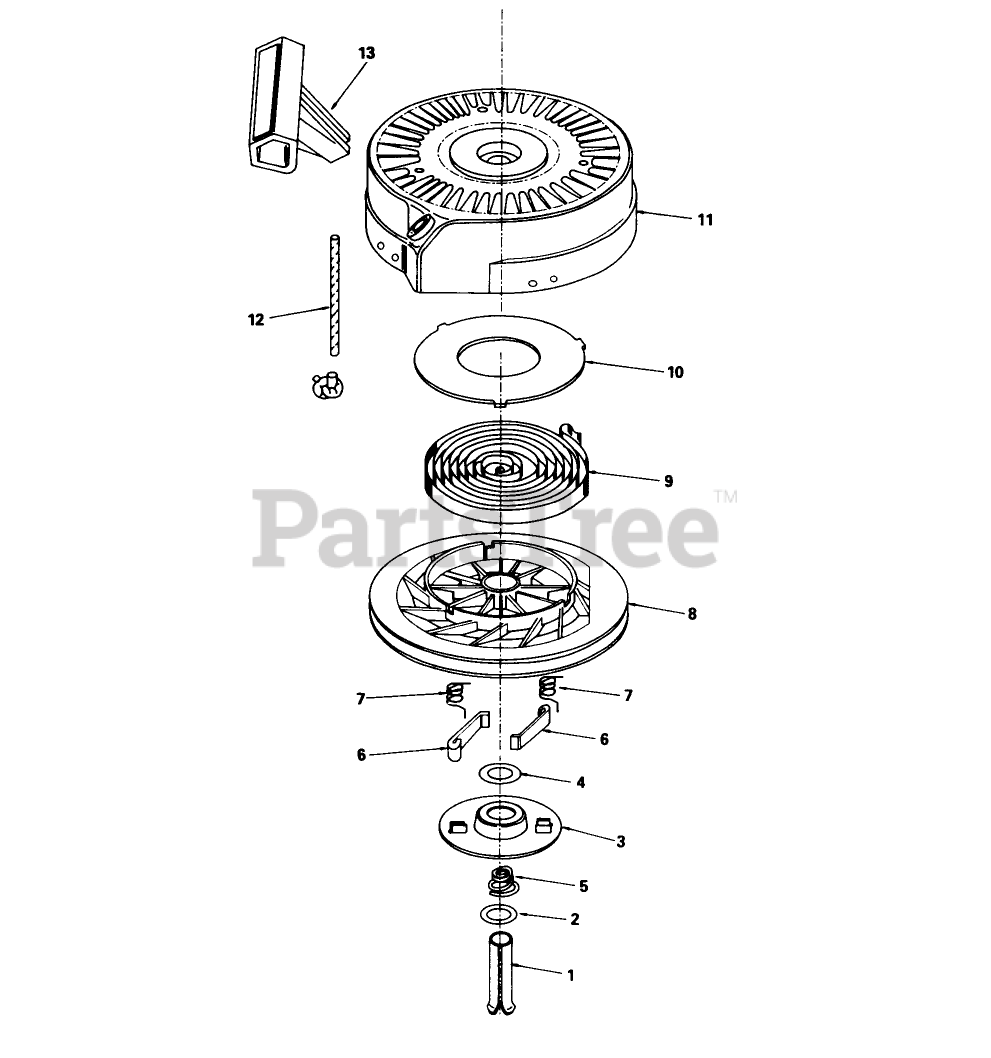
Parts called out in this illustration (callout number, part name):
1	Pin, Spring (Incl. Ref. #7)
2	Washer
3	Retainer
4	Washer
5	Brake Spring
6	Dog-Starter
7	Spring-Dog
8	Pulley
9	Rewind Spring
10	Cover-Spring
11	Housing-Starter
12	Rope-Starter (98 cut to length)
13	Handle-Starter
